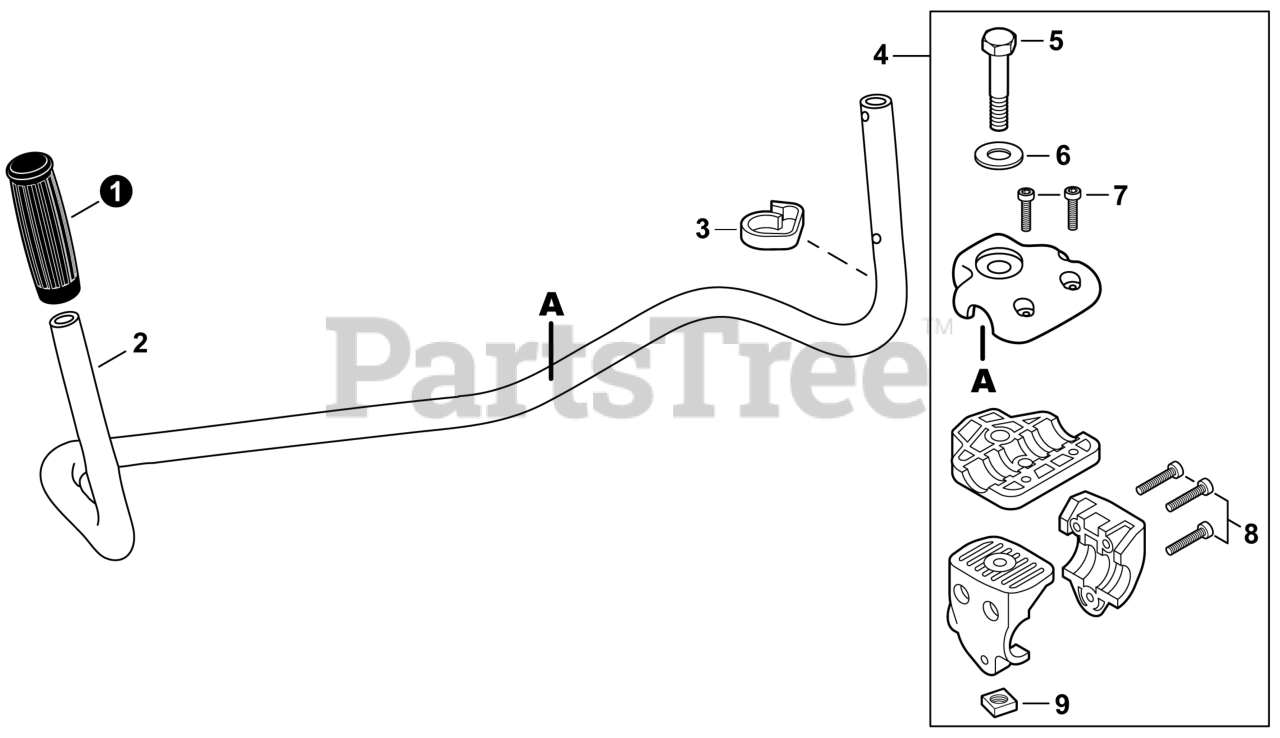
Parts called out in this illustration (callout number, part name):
1	GRIP, HANDLE
2	HANDLEBAR
3	CLIP, CABLE
4	BRACKET KIT, HANDLEBAR
5	BOLT 8x55
6	WASHER 8
7	BOLT, TORX 5x20
8	BOLT, TORX 5x25
9	NUT 8x1.25
